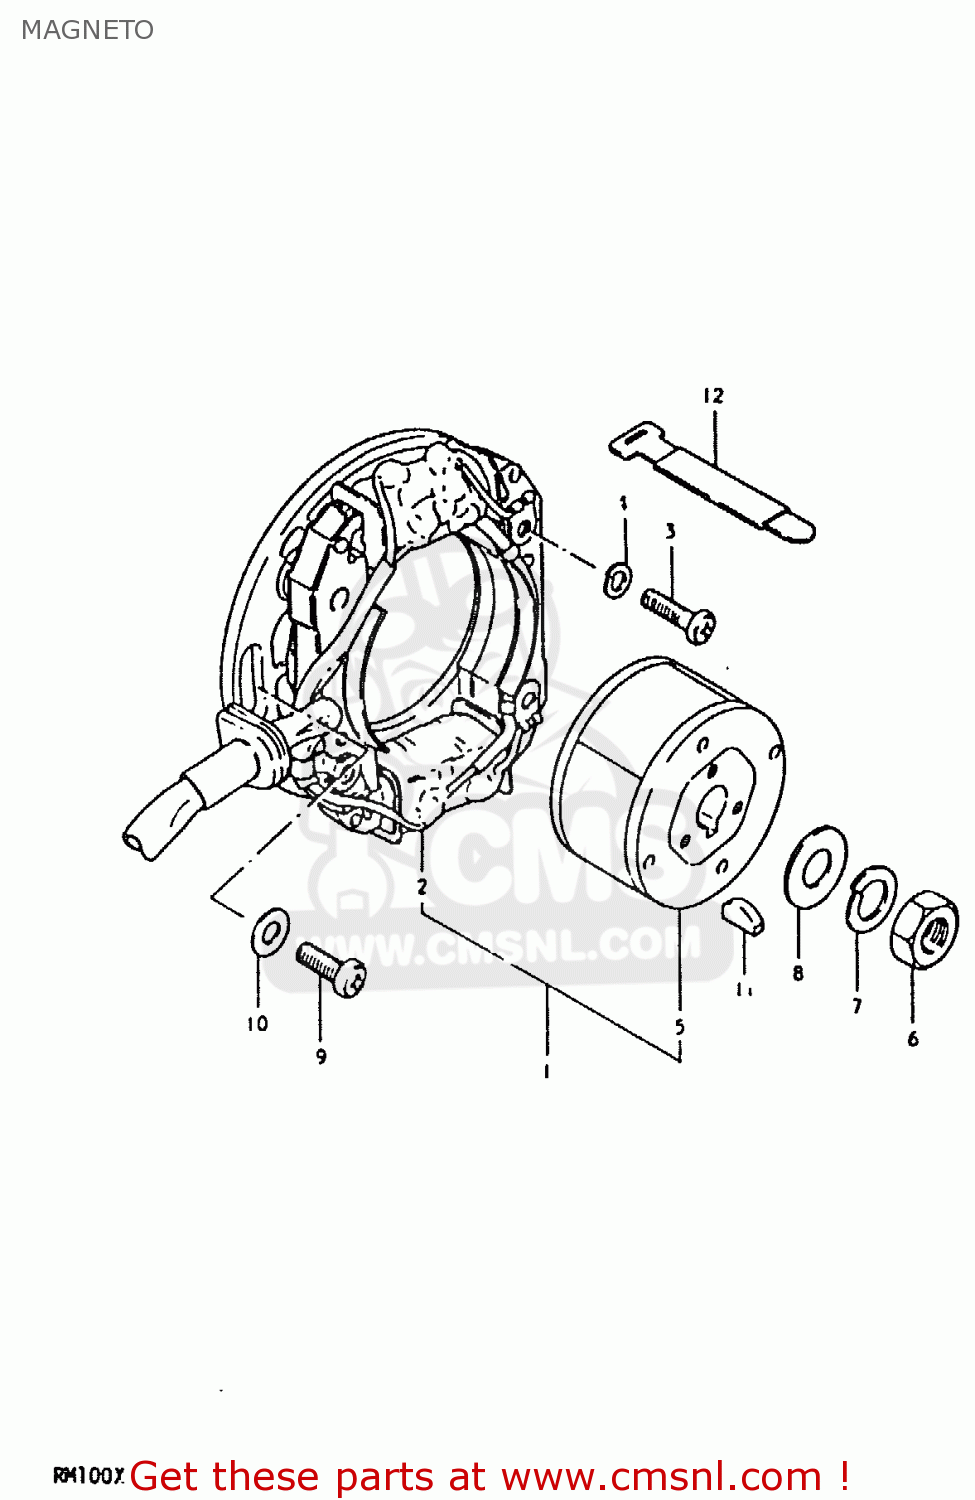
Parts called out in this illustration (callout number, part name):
1	MAGNETO ASSEMBLY
2	STATOR ASSEMBLY
3	SCREW 5X20
4	LOCK WASHER
5	ROTOR ASSEMBLY
6	NUT (10MM)
7	LOCK WASHER
8	WASHER
9	SCREW
10	WASHER
11	KEY 4MM
12	CLAMP
